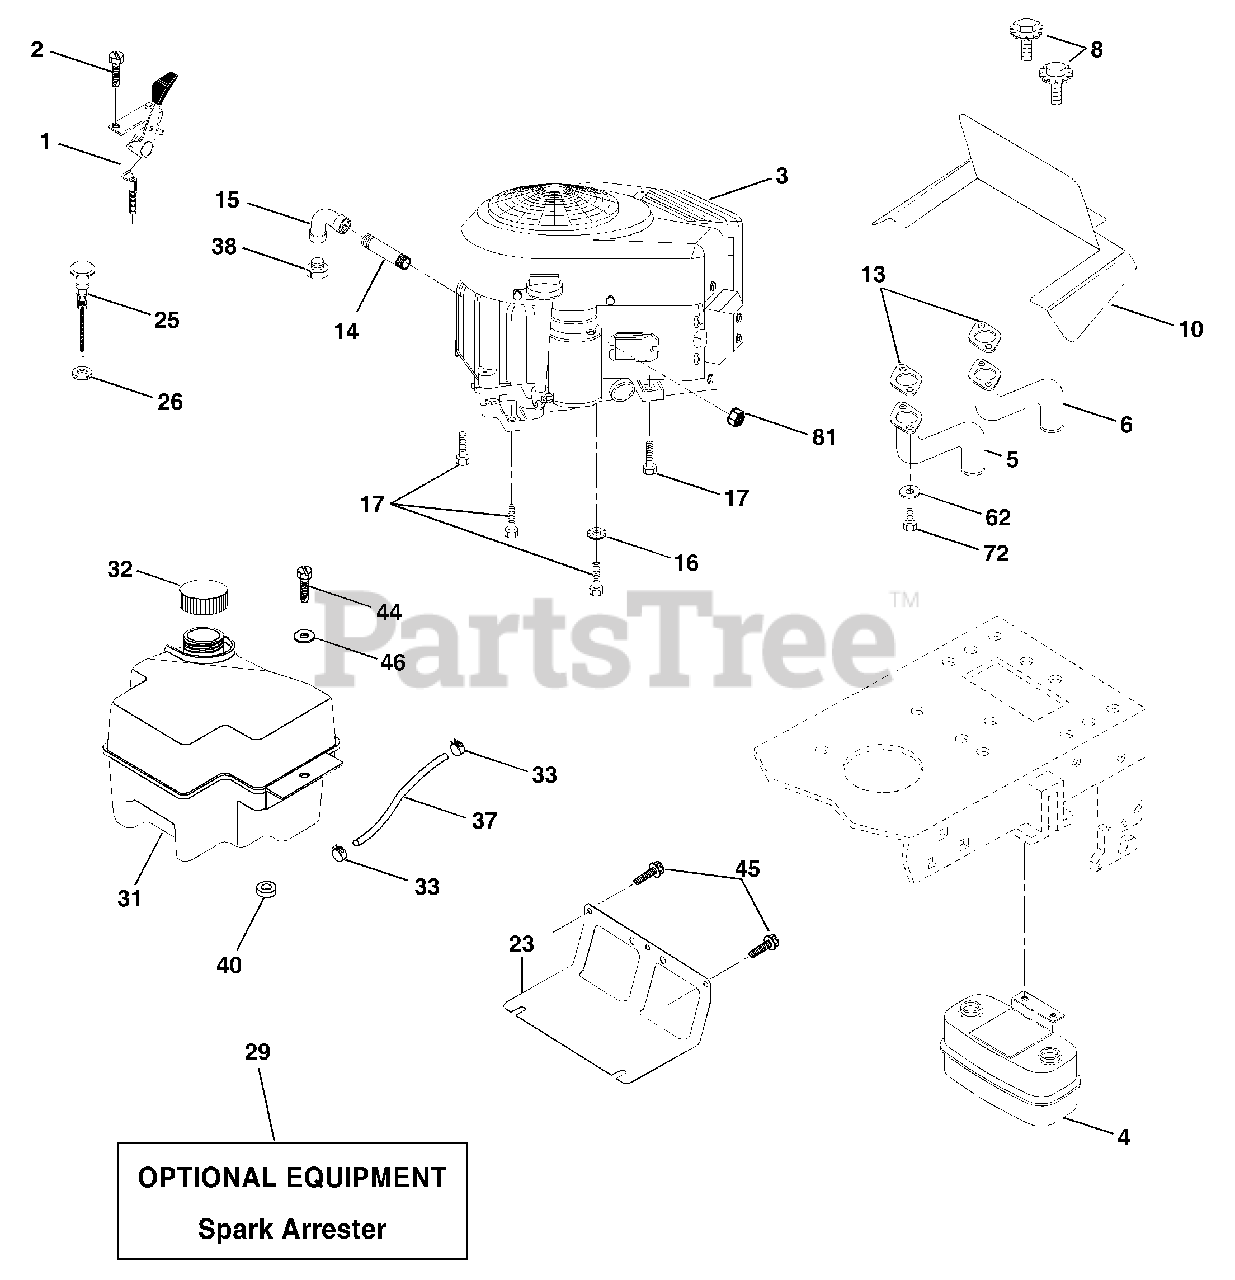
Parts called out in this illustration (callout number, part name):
1	Control, Throttle
2	Screw Hex Thd Cut 1/4-20 x 5/8
4	Muffler, Asm. Twin Lo-Tone
5	Pipe Exhaust Intek 20 RH
6	Pipe Exhaust Intek 20 LH
8	Bolt 5/16-18 UNC x 3/4
10	Shield Browing B&S Intek II
13	Muffler Gasket
14	Nipple, Pipe
15	Elbow, Standard 90°, 3/8-18 NPT
16	Washer, Lock Ext tooth 3/8
17	Screw Thdrol 3/8-16 x 1-1/2
23	Shield, Browning/Debris Guard
25	Control Choke
26	Nut Keps 3/8-24 UNF
29	Arrester, Spark
31	Tank, Fuel
32	Cap Gauge, Fuel
33	Clamp, Hose Blk
37	Line, Fuel 7.5
38	Plug, Oil Drain
40	Bushing Snap Nyl Blk Fuel Line
44	Screw Hex Wsh Thdrol 1/4-20 x 3/4
45	Screw Hex Wsh Thdrol 3/8-16 x 3/4
46	Washer 9/32 x 7/8 x 16 Ga.
62	Washer Lock Hvy Hlcl Spr 5/16
72	Screw Hex Hd Cap 5/16-18 x 3/4
81	Nut Keps Hex 1/4-20 Unc
